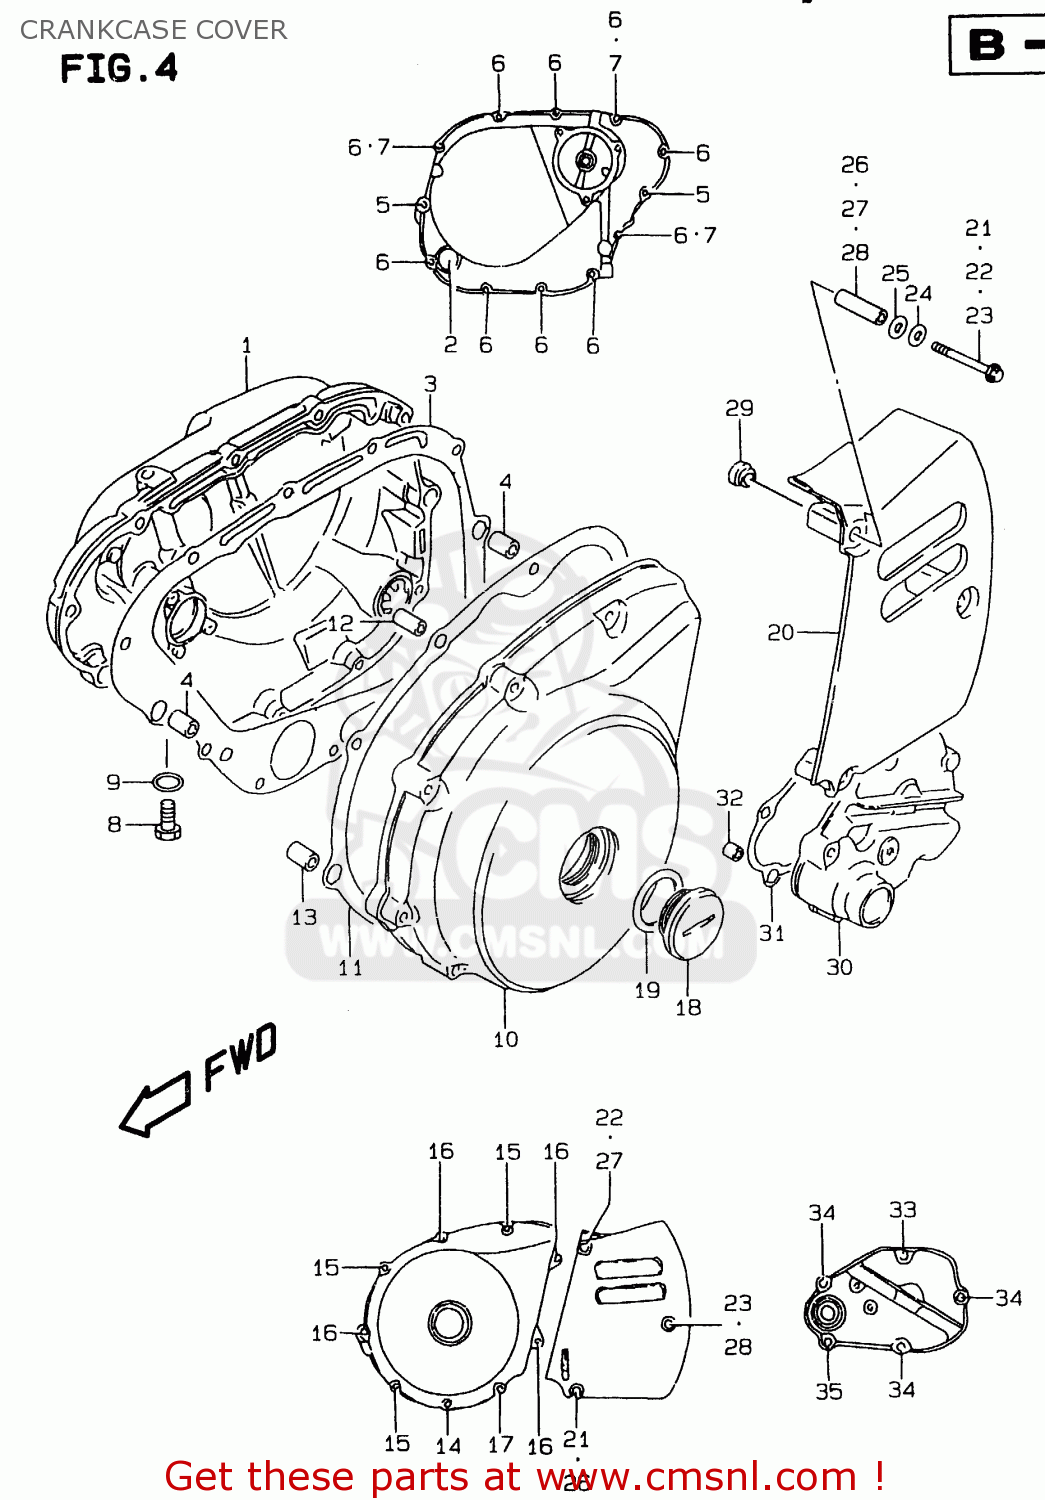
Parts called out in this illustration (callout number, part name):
1	COVER,CLUTCH
2	LENS,OIL LEVEL CHECK
3	GASKET,CLUTCH COVER (NAS)
4	PIN
5	BOLT
6	BOLT
7	GASKET(5.8X11X1.2) (NAS)
8	PLUG,12X9
9	GASKET(12.1X16.2X3.7) (NAS)
10	COVER,GENERATOR
11	GASKET,GENERATOR COVER (NAS)
12	PIN
13	PIN
14	BOLT
15	BOLT
16	BOLT
17	BOLT
18	PLUG,36X10
19	O RING(D:3.1,ID:32.7)
20	COVER,ENGINE SPROCKET
21	BOLT
22	BOLT
23	BOLT
24	WASHER
25	WASHER(8.7X15X2.1)
26	SPACER(6.5X9X31.5)
27	SPACER(6.5X9X38.3)
28	SPACER(6.5X9X41.3)
29	WASHER(8.7X16X5)
30	COVER,GEAR SHIFT
31	GASKET,GEAR SHIFT COVER (NAS)
32	PIN
33	BOLT
34	BOLT,G/S SWITC
35	BOLT
